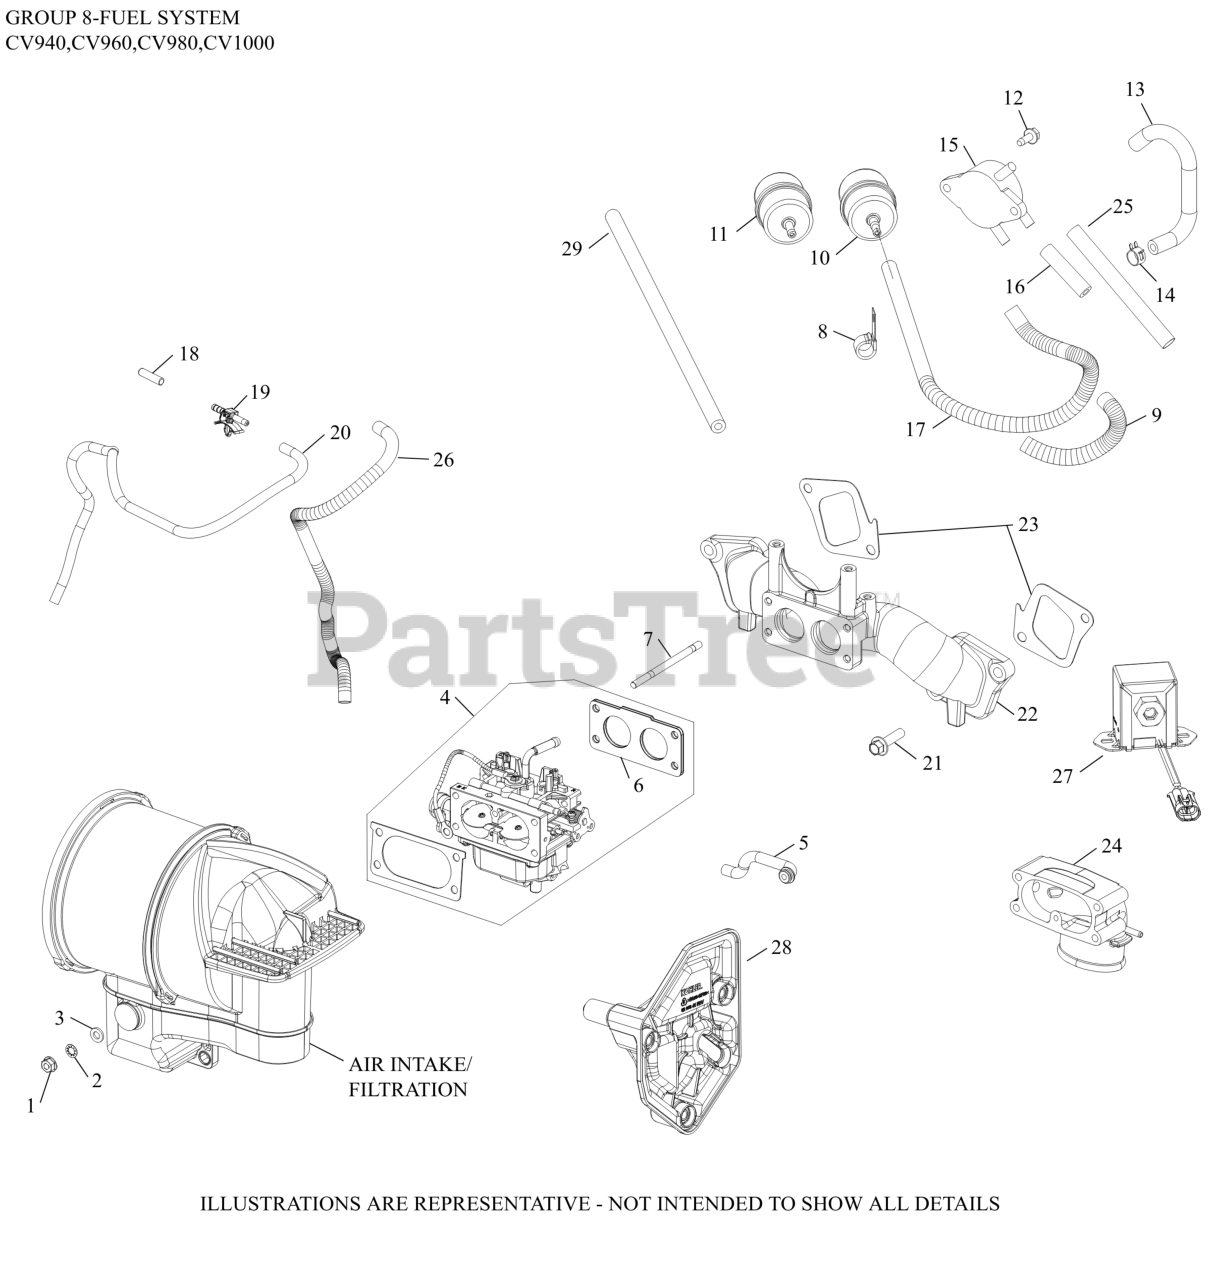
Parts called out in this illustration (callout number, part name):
1	NUT, FLG M6X1.0
2	WASHER, INT TOOTH LOCK 1/4"
3	WASHER, FLAT 1/4" (O.D. 1/2")
4	KIT,CARB (KEIHIN)
5	HOSE, CARBURETOR VENT
6	GASKET, CARBURETOR
7	STUD
8	CLIP, CABLE (KM)
9	SLEEVE, ANTI ABRASION-USE 25 431 12-S
11	FILTER, FUEL
13	HOSE, FUEL-LOW PERMEATION
14	CLAMP, HOSE (KM)-USE 25 237 31-S
15	PUMP, FUEL
16	LINE, FUEL 2" PUMP-FILTER
17	HOSE,LW PERM.FUEL 24.00"-USE 25 111 81-S
18	CAP, MASKING
19	CONNECTOR, EVAPORATIVE
20	HOSE, EVAPORATIVE 20"- (#24326143S)
21	SCREW, FLG M8X1.25X30
22	KIT, INTAKE MANIFOLD
23	GASKET, INTAKE MANIFOLD
NI	KIT, FLOAT REPAIR
NI	KIT, SOLENOID VALVE REPAIR
NI	KIT, OVERHAUL REPAIR
NI	KIT, HIGH ALTITUDE (4,000 - 8,000 FT)
NI	KIT, HIGH ALTITUDE (ABOVE 8000')
